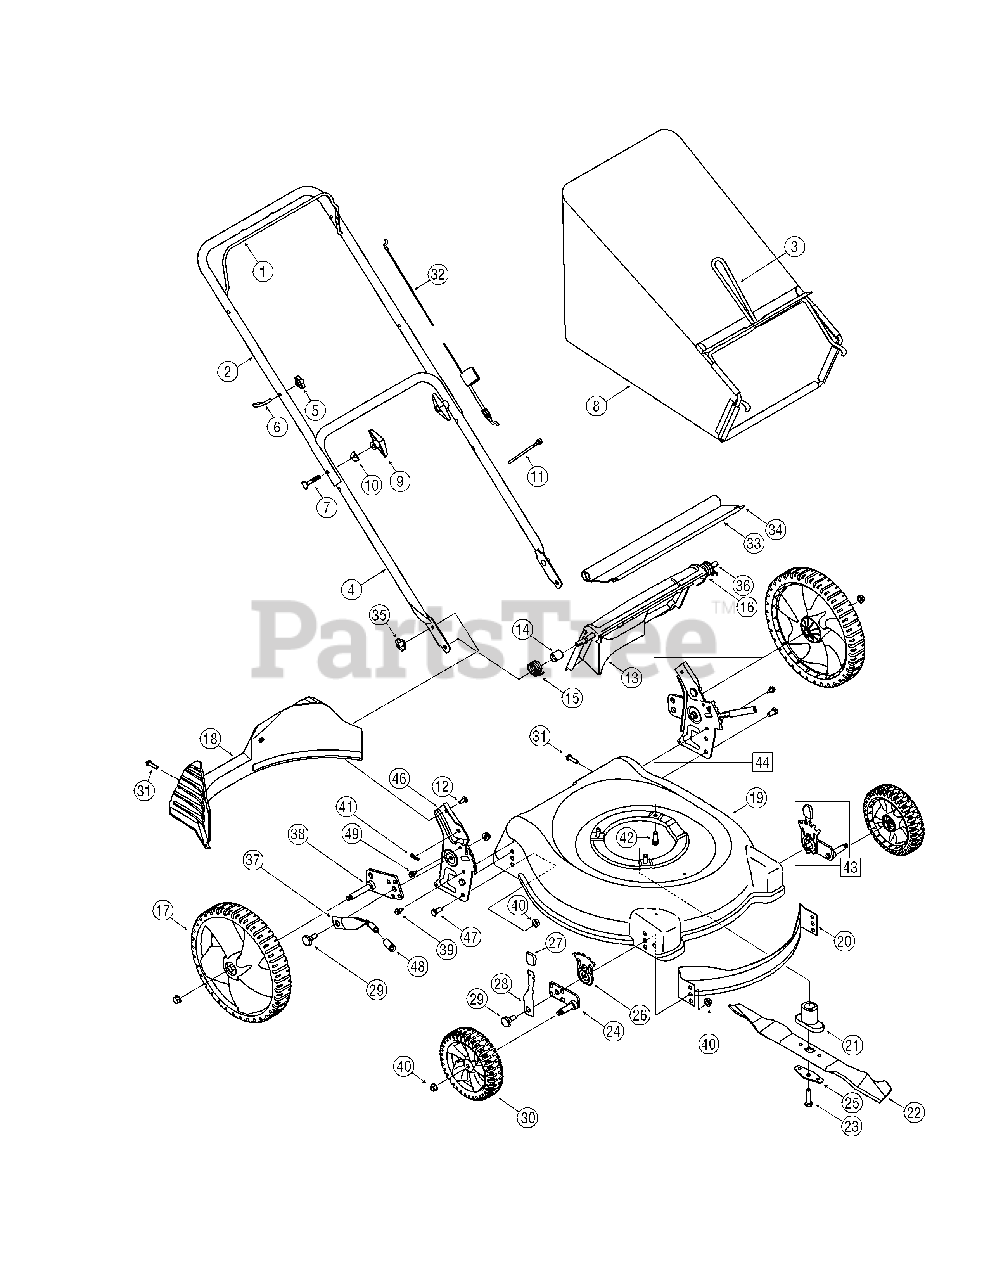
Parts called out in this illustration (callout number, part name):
5	Wing Nut
6	Rope Guide
7	Carriage Bolt ,5/16-18 x 2
8	Grass Bag Assembly
9	Hand Knob
10	Saddle Washer
11	Cable Tie
12	Carriage Bolt ,1/4-20
13	Rear Discharge Door
14	Spacer
15	Torsion Spring - LH
16	Torsion Spring - RH
17	Rear Wheel, 12 x 1.8
18	Rear Baffle
20	Front Baffle
21	Blade Adapter
22	Mulching Blade
23	Hex Screw, 3/8-24 x 2.5
24	Pivot Arm Assembly -RH
25	Blade Bell Support
26	Front Adjustment Plate
27	Adjustment Lever Knob
28	Spring Lever Assembly
29	Shoulder Screw
30	Front Wheel, 7 x 1.8
31	Screw, 1/4-15 x 1.250
32	Control Cable - 37.25"
33	Trailshield
34	Trailshield Wire
35	Wing Nut, 1/4-20
36	Rear Door Pivot Rod
37	Spring Lever
38	Pivot Arm Assembly - RH
39	AB Screw
40	Flange Lock Nut, 3/8-16
41	Hairpin Clip
42	TT Sems Screw, 3/8-16 x 1.0
43	Ht. Adj. Assy. Front - LH
44	Rear Handle Bracket Assy. - LH
45	Flange Lock Nut, 3/8-16
46	Handle Bracket Assembly - RH
47	Hex Screw, 3/8-16 x 0.75
48	Spring Lever Grip
49	Screw, 1/4-20 x .500
